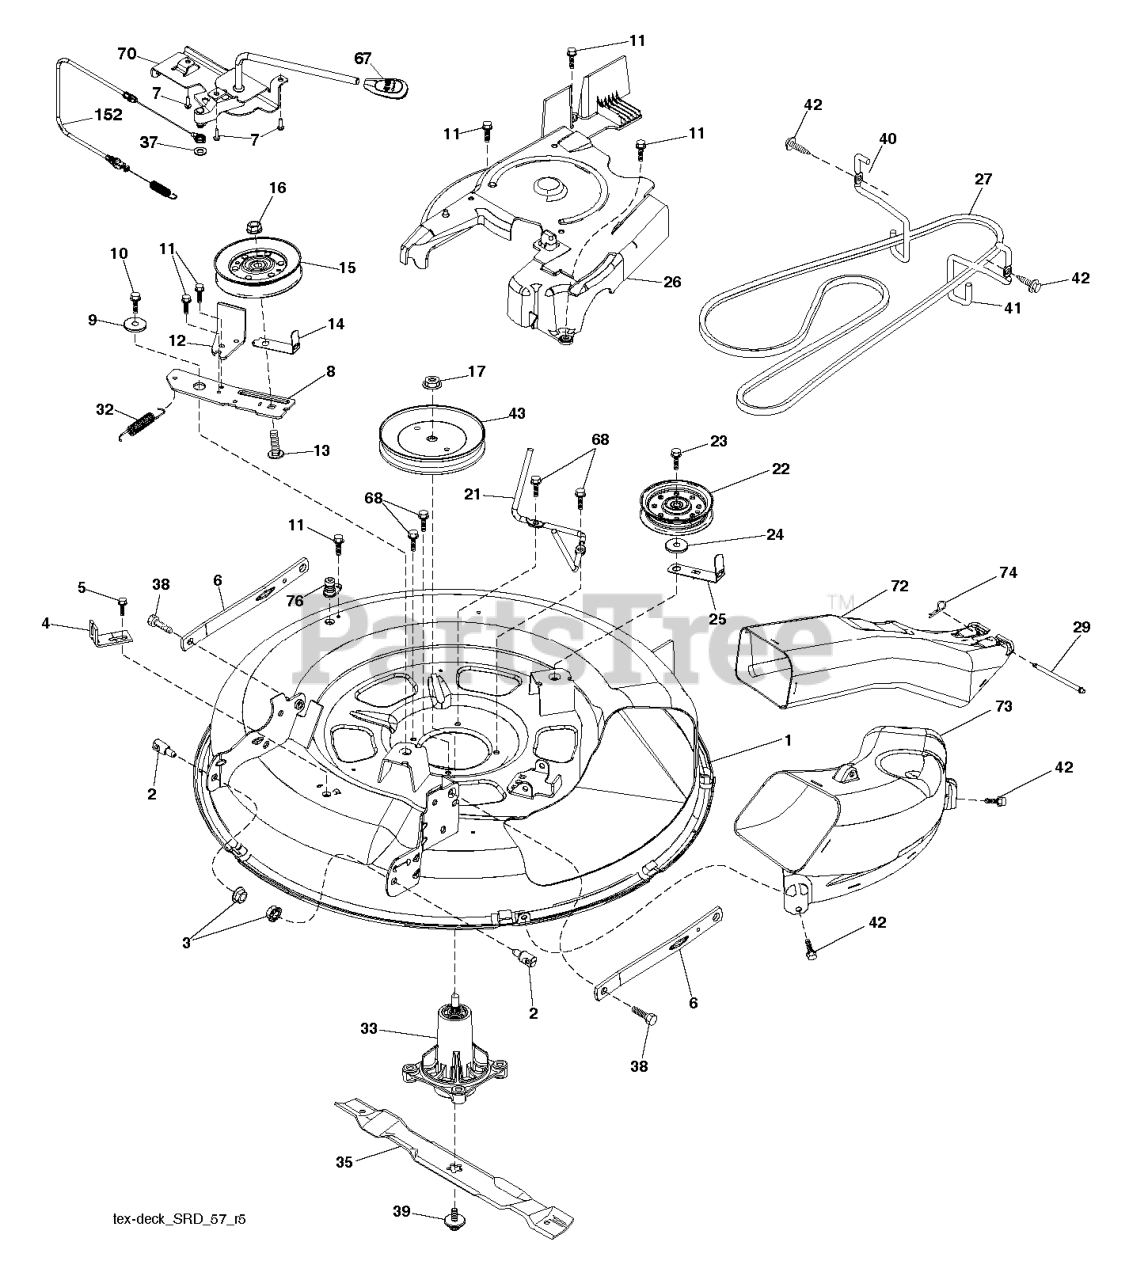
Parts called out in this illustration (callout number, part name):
1	DECK.SVC.WELDMNT.30"419272X418
2	STUD.FASTNER.W/ANTI-ROTATE
4	BRACKET.CLUTCH.CABLE
5	BOLT.5/16HEX.WHS.HD
6	ARMS.SUSP.MOWER.REAR.SRD
8	ARM.IDLER.30"SRD
9	SPACER.RETAINER
10	SCREW 3/8-16X1
11	SCREW.1/4-20X5/8
12	RP ARM.BRAKE.MOWER.38"LH.TEX
13	GSPW Bolts
14	KEEPER, BELT IDLER
15	PULLEY.IDLER.4.25
16	NUT LOCK FLG 3/8-16 UNC
21	KEEPER.BELT.MANDREL.30"
22	PULLEY.IDLER.FLAT.46.PR.DR.
23	BOLT;HEX_3/8-16 X 1.78.CLRZINC
25	KEEPER.BELT.30"SRD
26	COVER.ASM.MANDREL.30"
27	V-BELT.DRIVE.MOWER.30"
32	SPRING RETURN
33	KIT.MANDREL.NONGREASE.TALL
35	BLADE.MOWER.BAGGING.30"
37	WASHER
38	BOLT.SHOULDER
39	SCREW.SEMS.7/16-20X1.HEX.HEAD
40	KEEPER.BELT.ENGINE.LH.LT.SRD
41	KEEPER.BELT.ENGINE.RH.LT.SRD
42	SCREW, 3/8-16X3/4
43	PULLEY, MANDREL 6.5 PD
67	HANDLE.CLUTCH.CABLE.LT
68	BOLT.HEX.WASHR.HED.313-18X1.19
70	CLUTCH.ASM.MANUAL.LT.PRED
72	CHUTE.UPPER.SRD.30R"
73	CHUTE.LOWER.SRD.30R"
76	PORT.WASHOUT
152	CABLE.CLUTCH.MANUAL.
